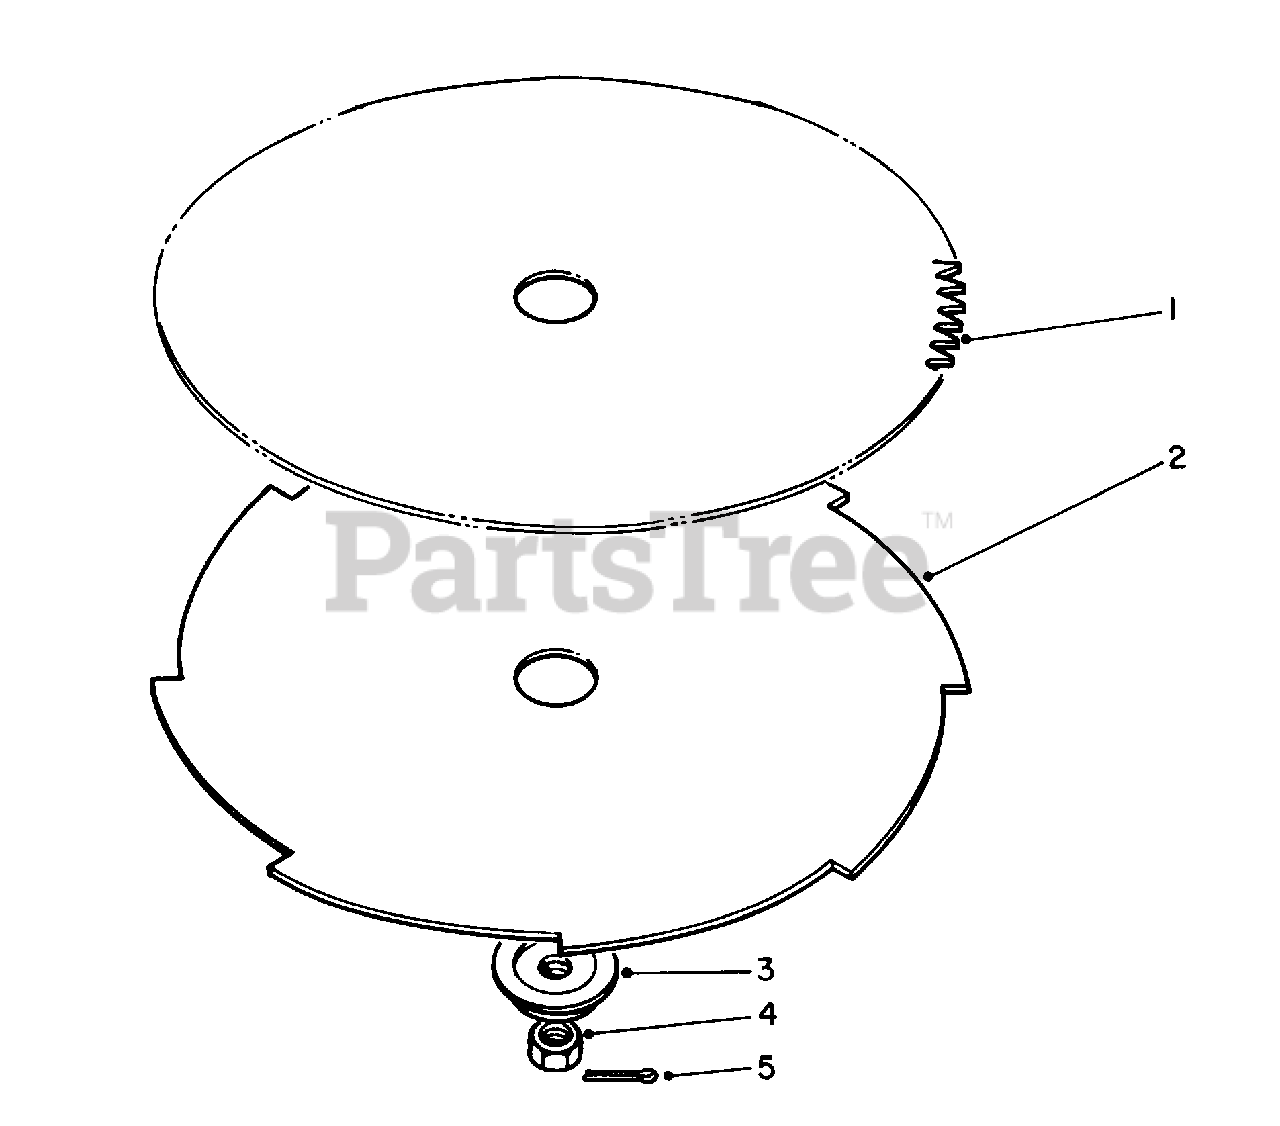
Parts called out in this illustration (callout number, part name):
1	8" Dia. Blade (80 Tooth)
2	8" Dia. Blade (8 Tooth)
3	Adapter-Blade
4	Nut L.H.
5	Pin Cotter
